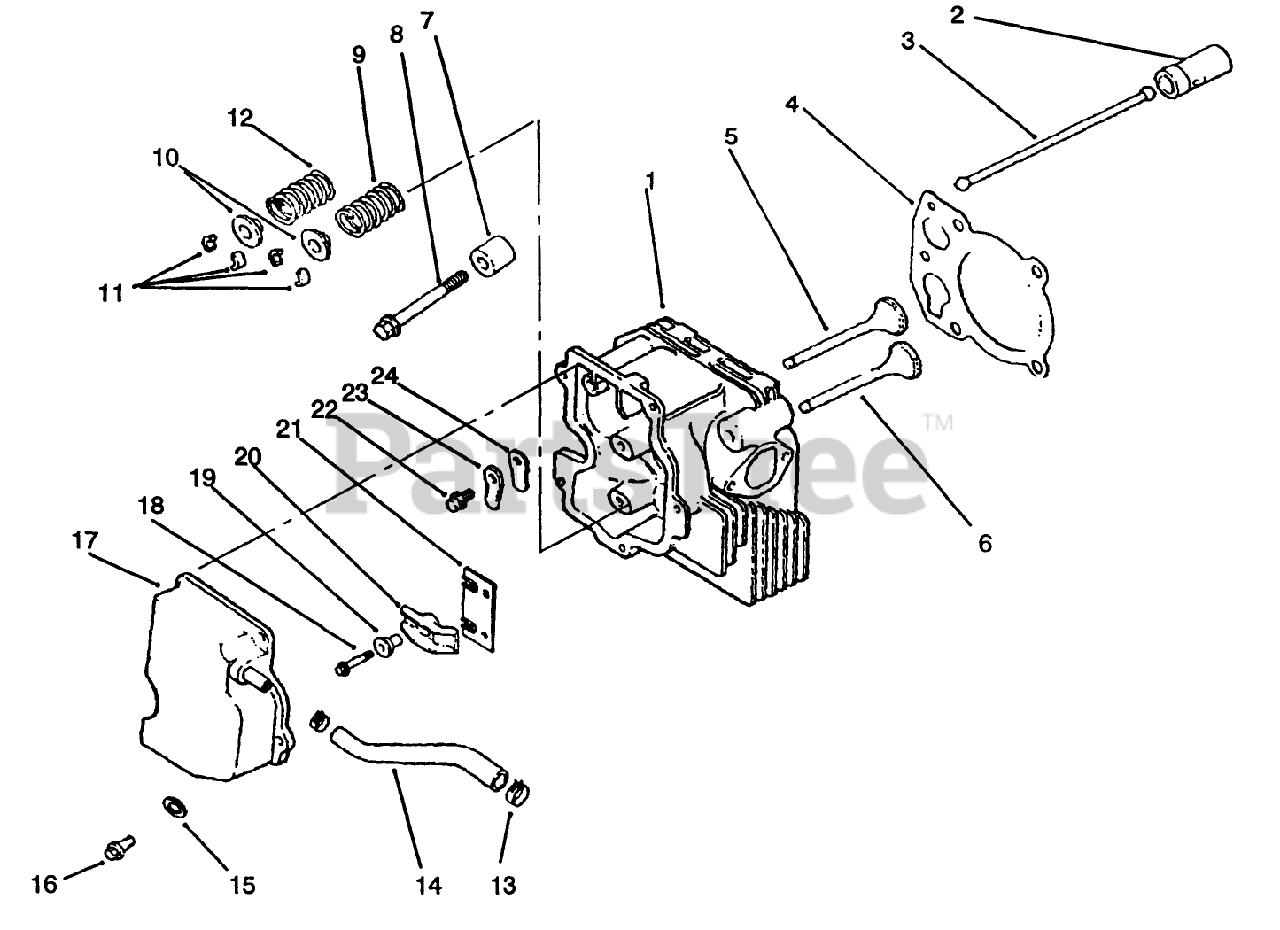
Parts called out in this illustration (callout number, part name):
1	Cylinder Head (Only On: 72042,72043,72062,72063)
2	Lifter-Valve
3	Rod-Push (Only On: 72042,72043,72062,72063)
4	Gasket-Cylinder Head (Only On: 72042, 72063, 72062, 72043)
5	Valve-Intake STD (Only On: 72042, 72063, 72062, 72043)
5	Valve-Intake .25 (Only On: 72042,72043,72062,72063)
6	Valve-Exhaust STD (Only On: 72042,72043,72062,72063)
6	Valve-Exhaust .25 (Only On: 72042, 72063, 72062, 72043)
7	Spacer-Head Bolt Exhaust (Only On: 72042, 72063, 72062, 72043)
8	Screw M10x1.5x80 (Only On: 72042, 72063, 72062, 72043)
9	Spring-Valve Exhaust (Only On: 72042,72043,72062,72063)
10	Cap-Valve Spring
11	Kit-Retainer
12	Spring-Valve Intake (Only On: 72042, 72063, 72062, 72043)
13	Clamp
14	Hose-Breather (Only On: 72042, 72063, 72062, 72043)
15	Washer-Flat (Only On: 72042, 72063, 72062, 72043)
17	Cover-Valve W/Nipple (Only On: 72042, 72063, 72062, 72043)
19	Ball-Rocker Pivot
20	Arm-Rocker
21	Plate-Guide (Only On: 72042, 72063, 72062, 72043)
23	Retainer-Reed
